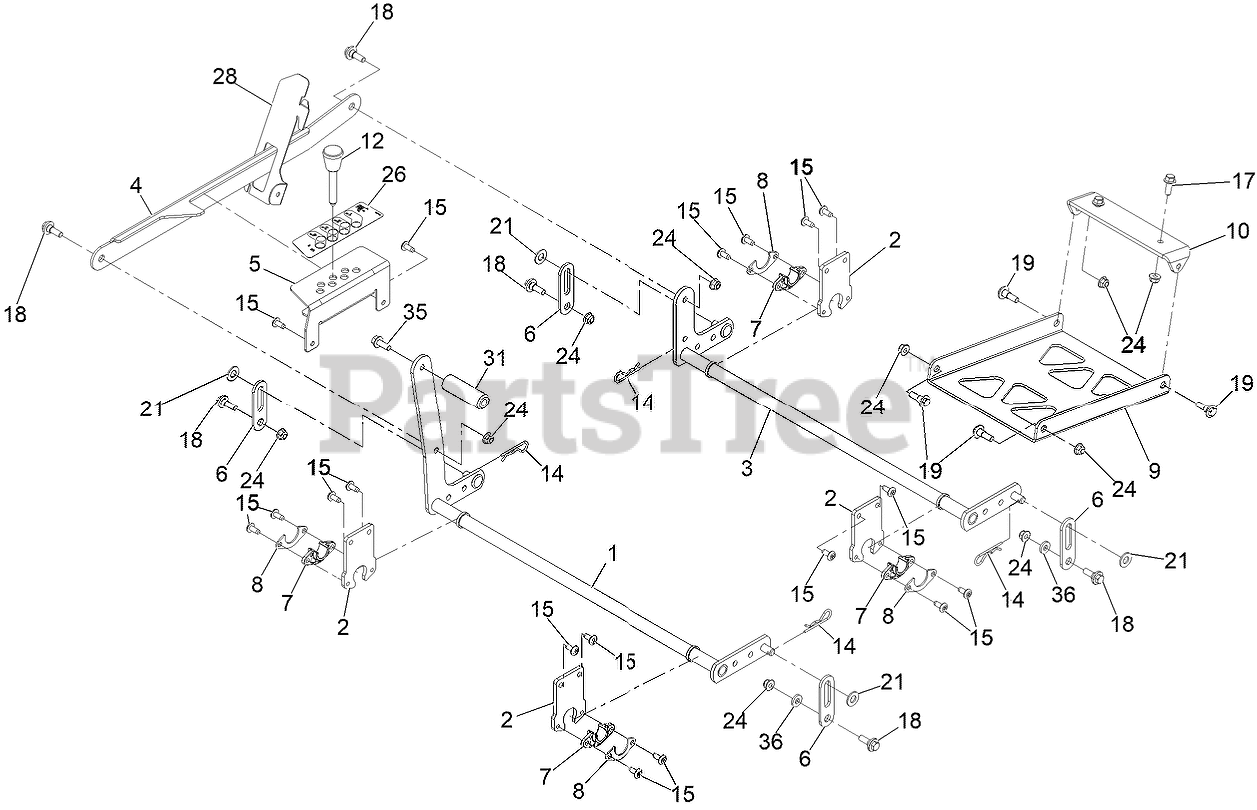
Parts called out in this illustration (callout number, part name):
1	PIVOT FRONT ASM
2	SUPPORT-CROSS, SHAFT
3	REAR PIVOT ASM
5	BRACKET-HOC
6	LINK-DECKLIFT
7	BEARING-FLANGE
8	GUSSET-DECK LIFT
9	PAN-DECK PIVOT
10	MOUNT - PAN
12	HOC PIN ASM
14	PIN-COTTER
17	SCREW-HHF 3/8-16 X 1
18	SCREW-SHOULDER
19	SCREW-SHOULDER, HHF
21	WASHER-FLAT
24	NUT-HF, NI
26	DECAL-HOC
28	BRACKET-HOC
31	PEDAL-FOOT LIFT
35	SCREW-HHF
